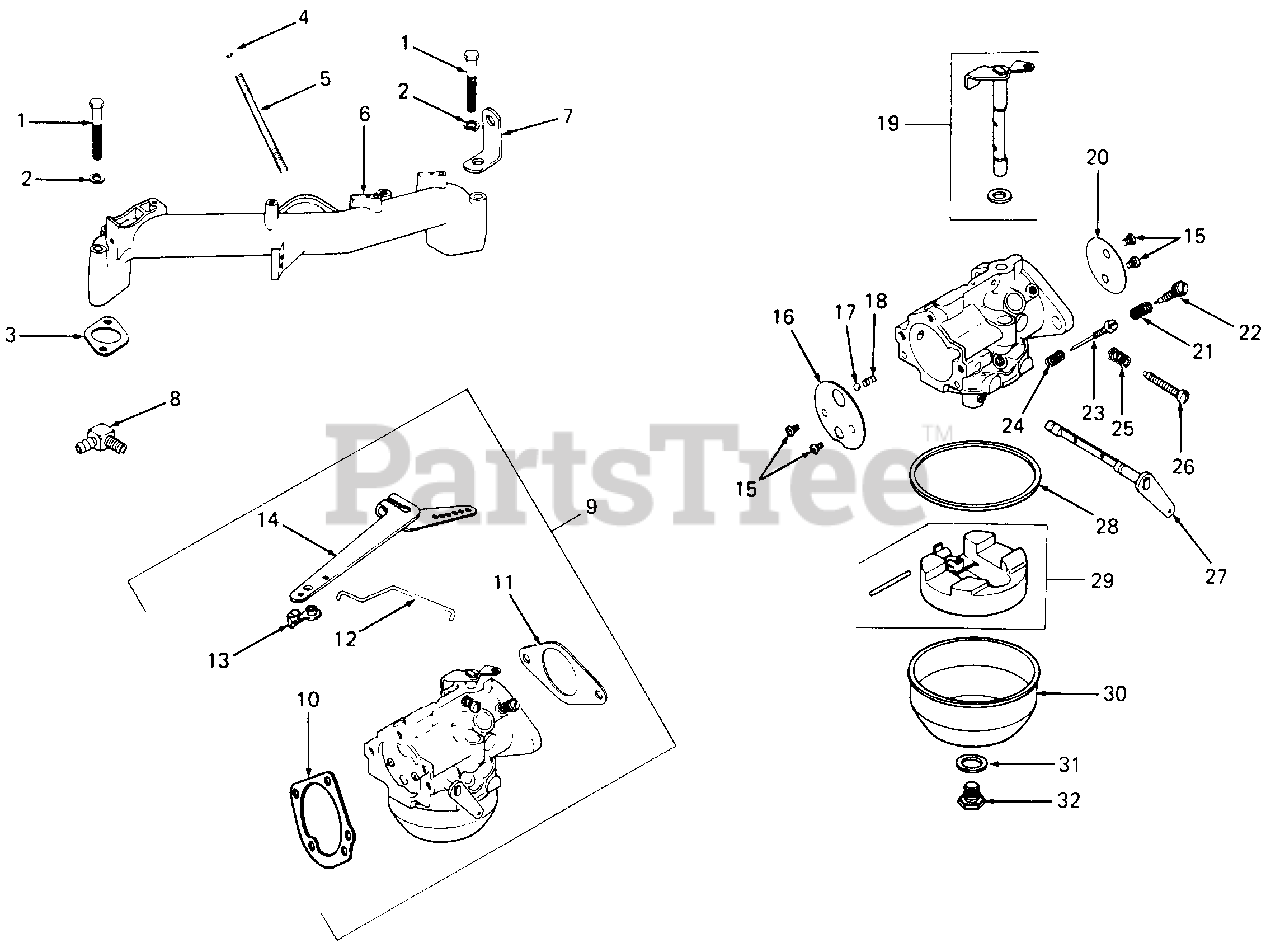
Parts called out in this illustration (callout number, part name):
1	Screw, Hex Cap, 5/16-18 X 2.75 Lg
2	Washer, Lock, 5/16
3	Gasket, Intake
4	Nut, Hex Jam, 5/16-18
5	Stud, 5/16-18 X 1.0 Lg
6	Manifold, Intake
7	Strap, Lifting
8	Connector, 90
9	Kit, Carburetor w/Linkage
10	Gasket, Air Cleaner
11	Gasket, Carburetor
12	Kit, Governor Linkage
13	Bushing, Governor Linkage
14	Arm, Governor
15	Screw, Throttle & Choke Plate
16	Plate, Choke
17	Ball, Choke Friction
18	Spring, Choke Friction
19	Shaft, Throttle w/Lever & Seal
20	Plate, Throttle
21	Spring, Idle Fuel
22	Needle, Idle Fuel Adj
23	Needle, Main Fuel
24	Spring, Main Fuel
25	Spring, Idle Speed
26	Screw, Idle Speed Adj
27	Lever, Choke
28	Gasket, Bowl
31	Gasket, Bowl Retainer Screw
32	Screw, Bowl Retainer
